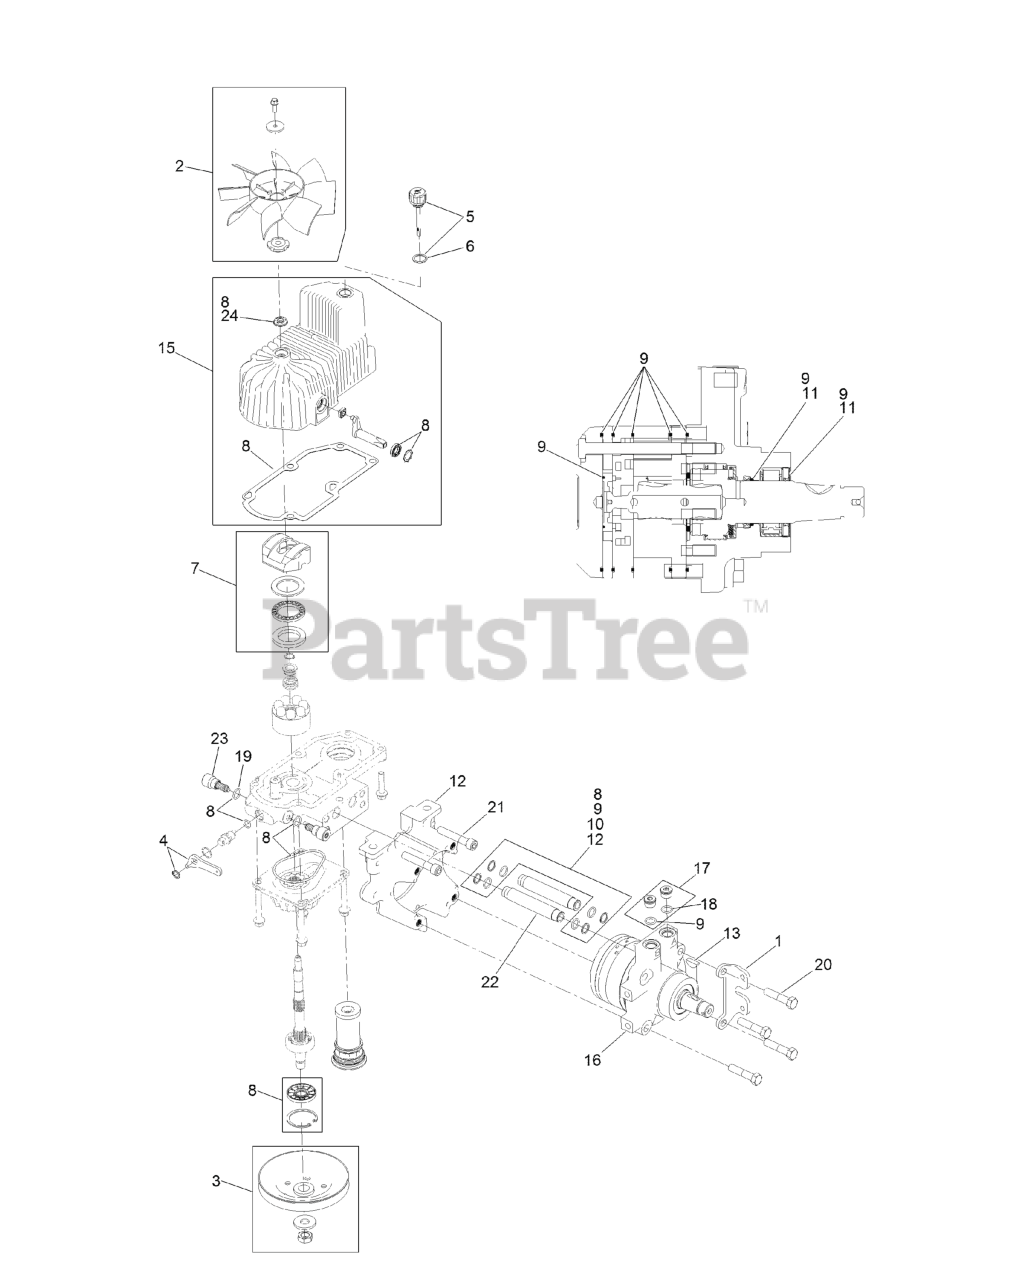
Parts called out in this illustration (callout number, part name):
1	MOUNT-SHOE, HORSE
2	FAN KIT
3	PULLEY KIT
4	HANDLE-BYPASS VALVE, HYDRO
5	DIPSTICK-HYDRO W/GASKET
6	GASKET-DIPSTICK, HYDRO
7	SWASH BLOCK KIT
8	PUMP SEAL KIT
9	MOTOR SEAL KIT
10	TUBE SEAL KIT
11	OUTPUT SHAFT SEAL KIT
12	NOSE CUP-UHT
13	KEY-WOODRUFF
15	HOUSING-HYDRO, RH
16	MOTOR-HYDRAULIC RH 240CC
17	MAGNETIC PLUGS SERVICE KIT
19	O-RING-CHECK VALVE
20	SCREW HH
21	SCREW-HSH
22	HYDRAULIC TUBE KIT
23	SHOCK VALVE, 12CC HYDRO
24	SEAL-FAN DRIVE
25	Kit, Pump Section 12Cc RH
26	KIT, ROTATING GRP 12CC RH
